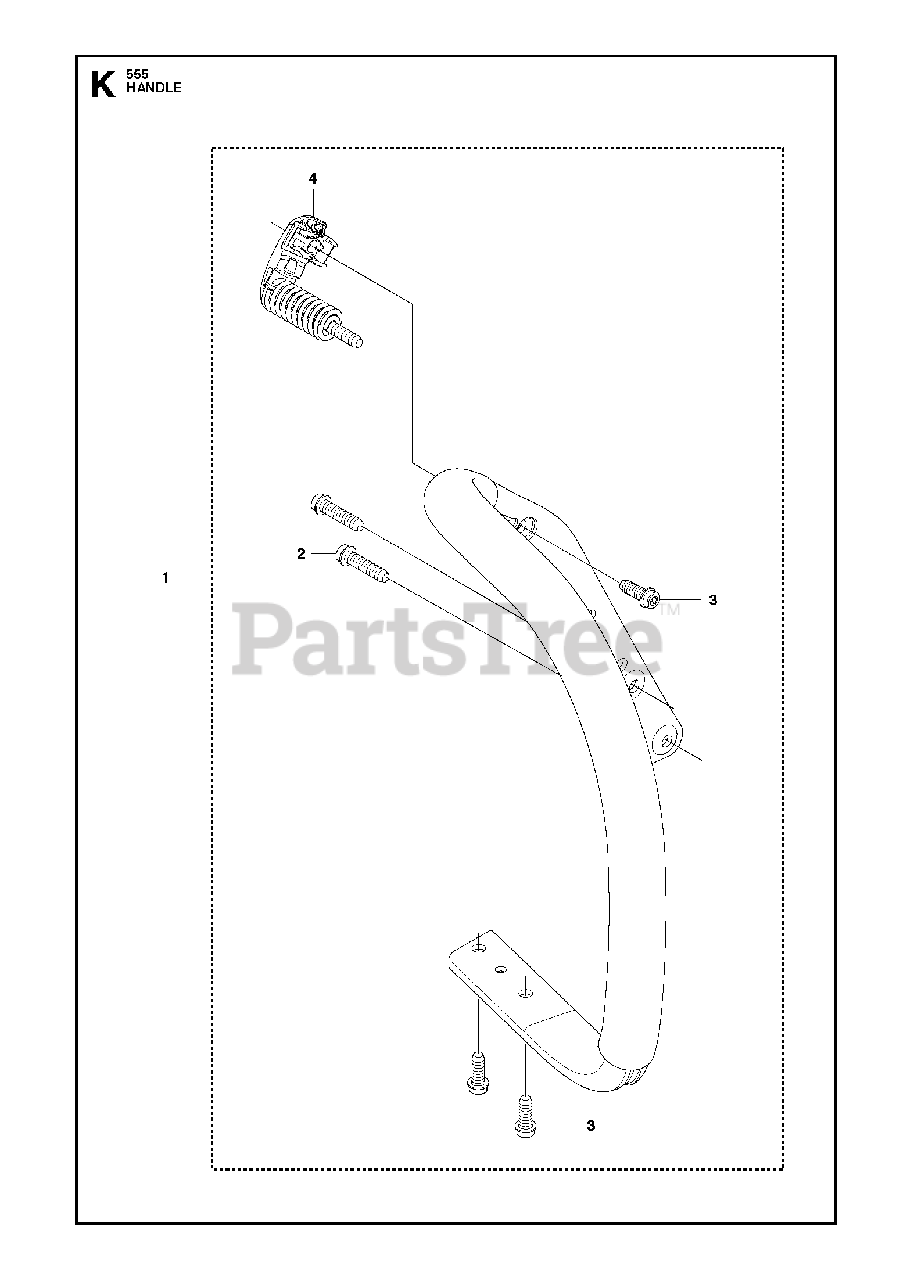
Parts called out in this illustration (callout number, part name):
1	FRONT HANDLE
2	SCREW
3	SCREW IHSCFT
4	ANTIVIBRATION ELEMENT
